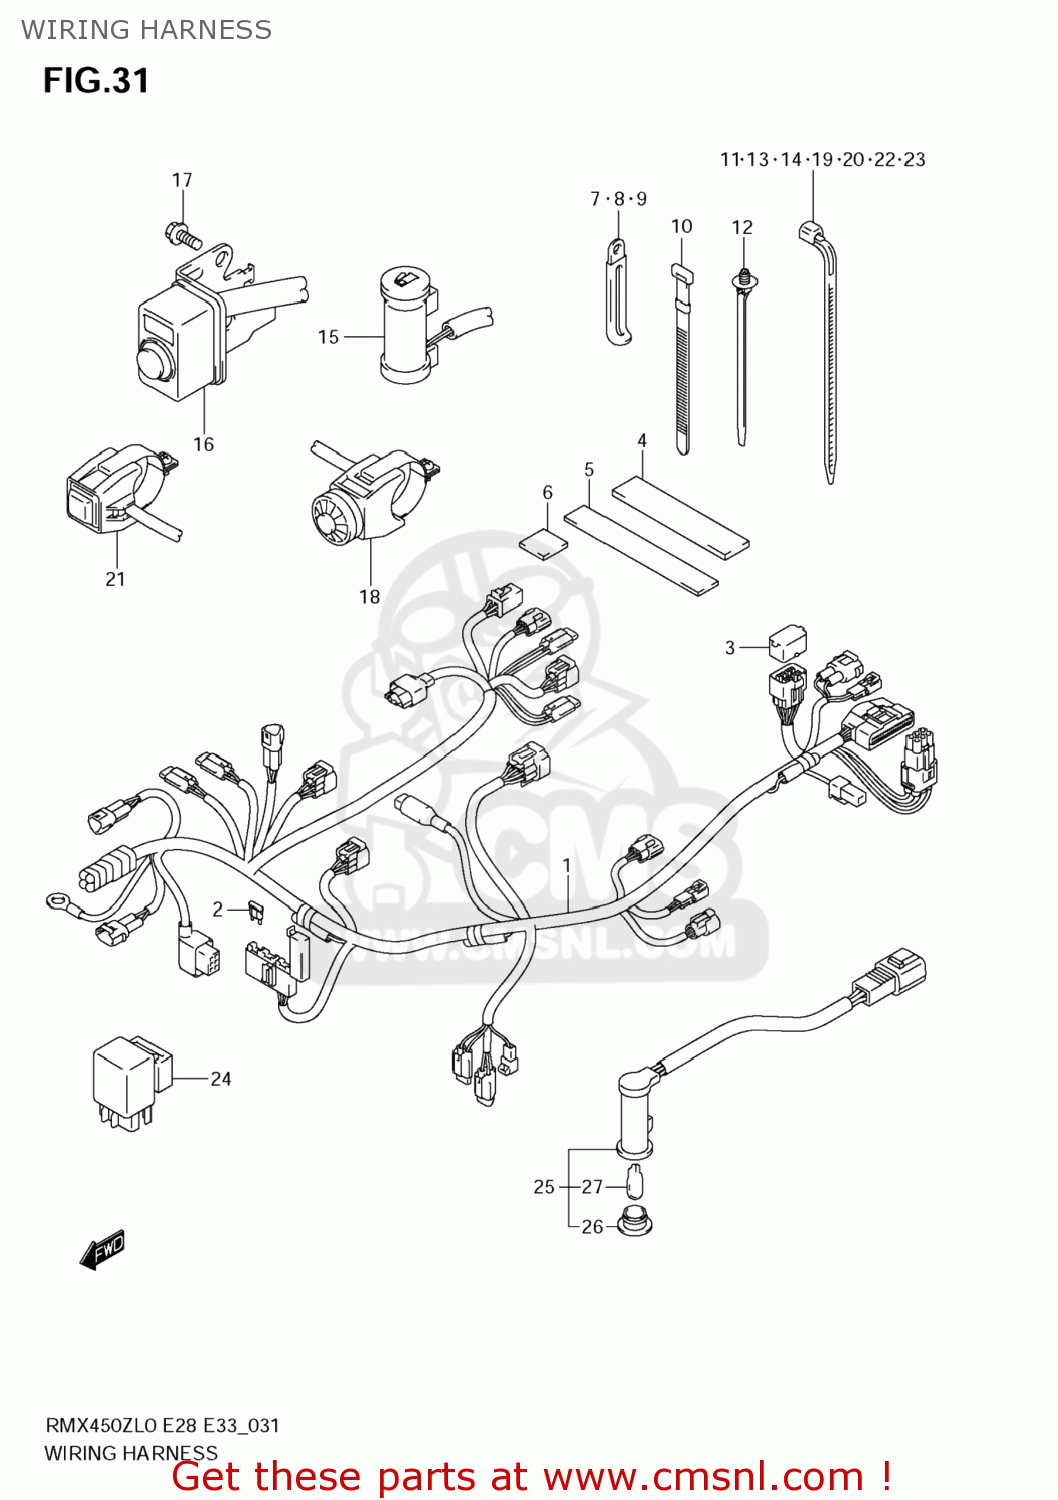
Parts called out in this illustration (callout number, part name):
1	HARNESS,WIRING
2	FUSE(15A)
3	CAP,TS
4	PROTECTOR(20X90)X1.0
5	PROTECTOR,WIRING HARNESS
6	PROTECTOR,20X2
7	CLAMP(L:80)
8	CLAMP(L:135)
9	CLAMP(L:45)
10	CLAMP(L:95)
11	CLAMP(L:125)
12	CLAMP(L:154)
13	CLAMP(L:165)
14	CLAMP(L:235)
15	LAMP ASSY,FUEL
16	SWITCH ASSY,IGNITION
17	BOLT
18	SWITCH ASSY,STARTER MOTOR
19	CLAMP(L:95)
20	CLAMP(L:125)
21	SWITCH ASSY,ENGINE STOP
22	CLAMP(L:95)
23	CLAMP(L:125)
24	RELAY ASSY,HEADLAMP
25	LAMP ASSY,FI INDICATOR
26	LENS(RED)
27	BULB(12V3.4W,T10)
